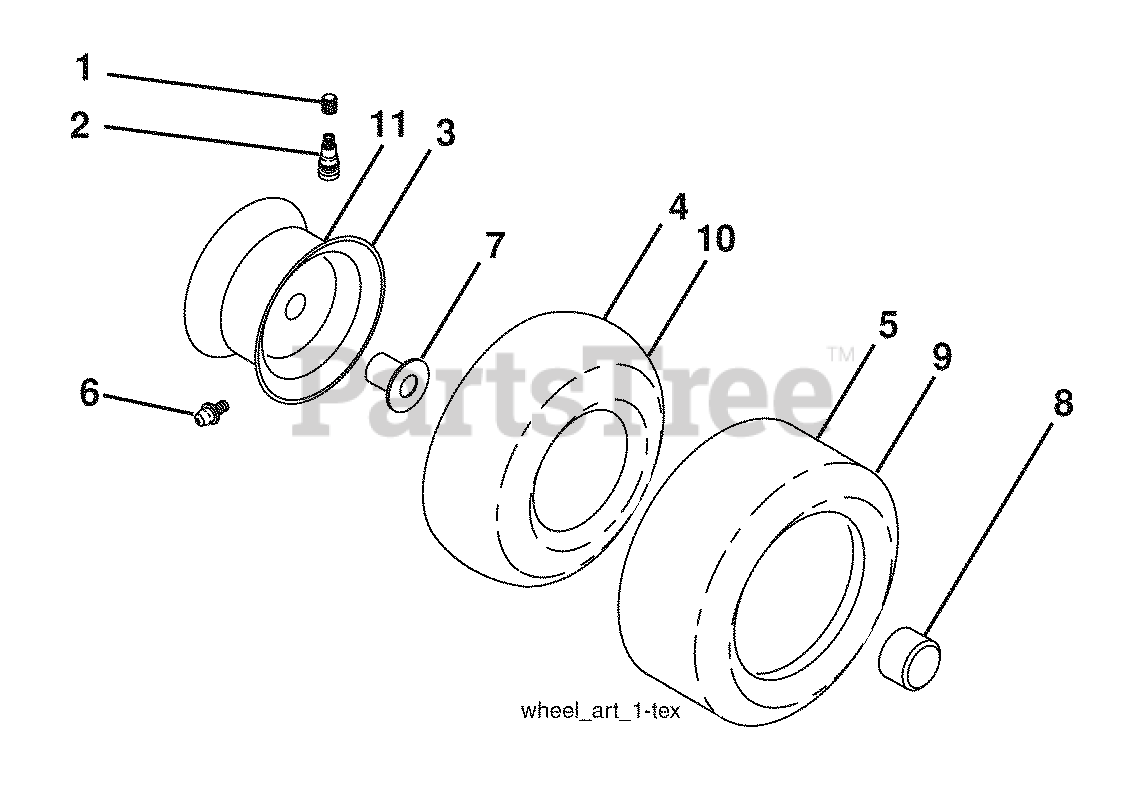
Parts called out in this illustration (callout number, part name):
1	Cap Valve Tire
2	Stem Valve
3	Rim Asm 6" Front
4	Tube Front
5	Tire F T 15 x 6 0 - 6
6	Fitting Grease
7	Bearing Flange
8	Cap Axle Blk 1 50 x 1 00
9	Tire R 18 x 9.5-8 Turf Saver
10	Tube Rear
11	Rim Asm 8" Rear
